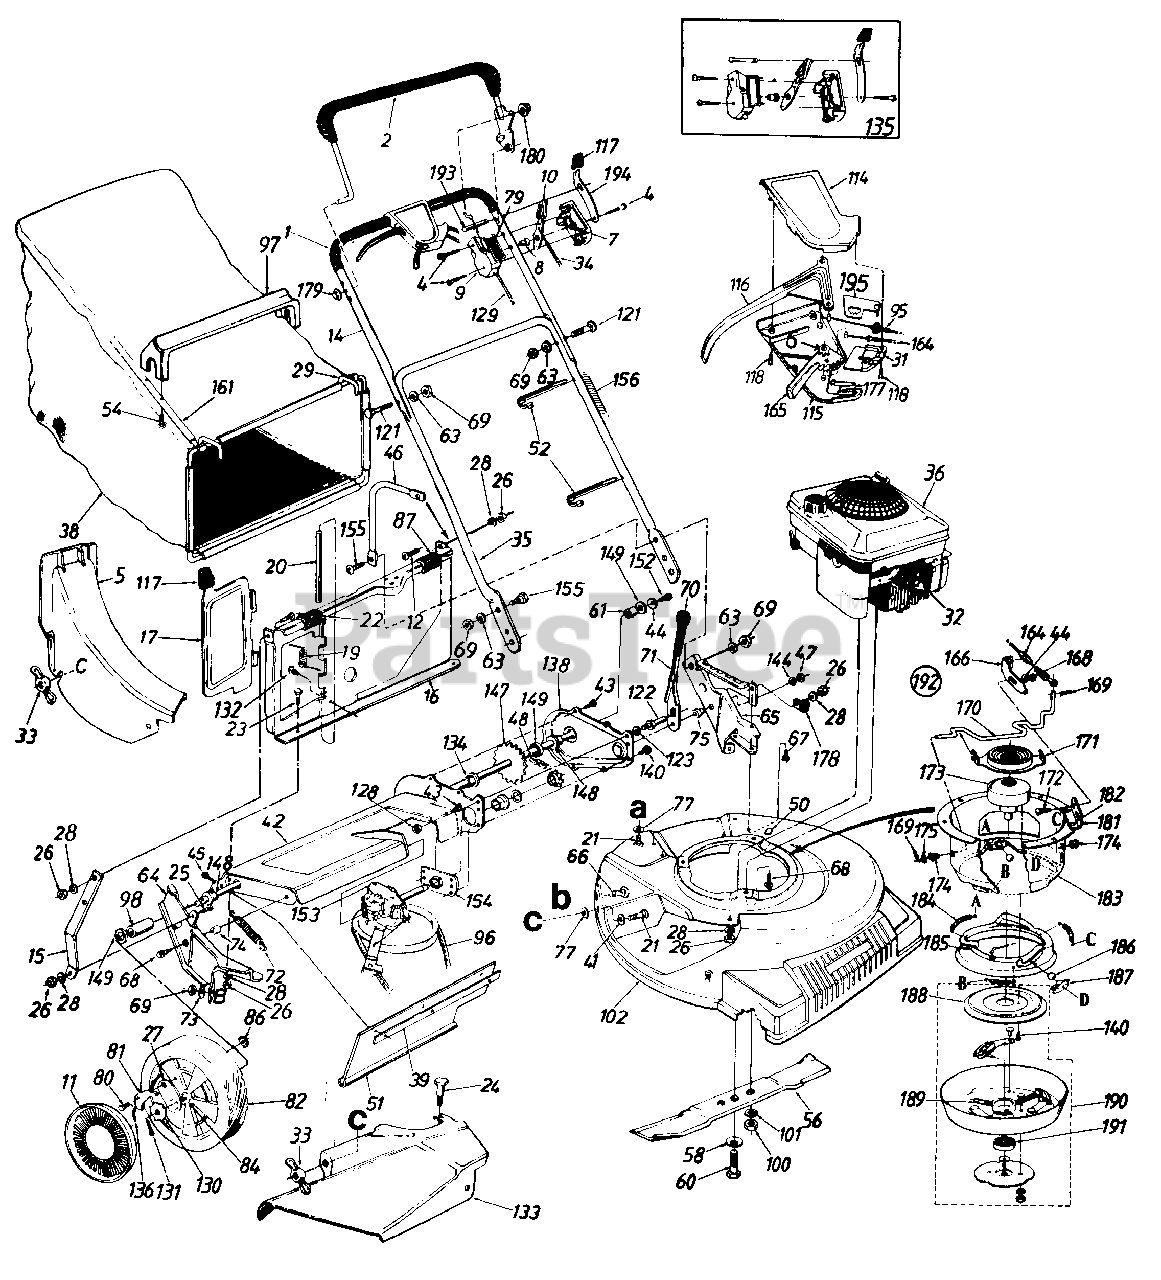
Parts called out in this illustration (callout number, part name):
1	Grip
2	Control Handle Ass'y. L.H.
4	Truss Mach. Scr. #12 x 1.50" Lg.
5	Rear Discharge Chute Ass'y.
6	3 Tooth Rack Gear Insert
7	Control Panel Half
8	Control Disc Pin
9	Clutch Panel Half
10	Throttle Control Lever
11	Hub Cap
12	Truss Mach. Scr. 1/4-20 x .62" Lg.
14	Upper Handle
19	Torsion Spring
20	Pivot Pin
21	Carriage Bolt 1/4-20 x .62"
22	Truss Mach. Scr. 1/4-20 x .75" Lg.
23	Hex Bolt 1/4-20 x .5" Lg.
24	Shoulder Bolt Special
25	Hex Bolt 1/4-20 x .62" Lg.
26	Hex Nut 1/4-20 Thd.
27	Pawl Plate
28	L-Wash. 1/4" I.D.
31	S.P. Control Cover
32	Spark Plug Insulator
33	Wing Nut
34	Throttle Control Wire 61"
35	Lower Handle
36	Engine
38	Grass Bag
39	Retaining Strip
41	Fl-Wash. .344" I.D. x .62".
44	Bell-Wash. 1/4" I.D.
45	Hex AB-Tap Scr. 1/4 X .62"
46	Catcher Panel Support Brkt.
47	Hex Patch L-Nut 3/8-24 Thd.
48	#48 Chain .500" Pitch x 30 Links
51	Rear Flap 3.75" x 17.30" Lg.
52	Cable Tie
54	Hex AB-Tap Scr. #12 x 1.25" Lg.
56	21" Blade
58	Bell-Wash..46" I.D.
60	Hex Bolt 7/16-20 x 2.0"
61	Spacer.513" I.D.
63	L-Wash. 5/16" I.D.
64	R.H. Handle Wheel Brkt. Ass'y.
65	L.H. Handle Wheel Brkt. Ass'y.
66	Carriage Bolt 5/16-18 x .62"
67	Hex B-Tap Scr. 5/16-18
68	Hex TT-Tap Scr. 3/8-16
69	Hex Nut 5/16-18 Thd.
71	Height Adj. Lever
72	Extension Spring 3.80" Lg.
73	Bell-Wash. 5/16" I.D.
74	Spacer.383" I.D.
75	Shld. Spacer .5" Dia.
77	Bolt Retainer 1/4 X .50" O.D.
79	Control Label
80	Shld. Scr. .342" Dia. x .268
81	Pawl
82	Wheel Ass'y. Comp. Rear
84	Sleeve Bearing 1/2" I.D.
86	Flat Nut 1/4-20 Thd.
87	Panel Clip
95	S.P. Cable 50" Lg.
96	"V"-Belt
97	Bag Handle
98	Sleeve.526" I.D.
100	Hex Nut 3/8-24 Thd. (Gr. 8)
101	L-Wash. 3/8" I.D.
115	Self-Propelled Control Cover
116	Control Lever
117	Door Grip
118	Fl-"C"-Sunk Hd. Tap Scr. #10 x .75' Lg.
121	Curved Carr. Bolt 5/16-18 x 1.38" Lg.
122	Shld. Pin 1.43" Lg.
123	L-Wash. 3/8" I.D.
128	Hex Jam Nut 3/8-24 Thd.
129	Control Cable 49"
130	Ratchet Wheel 1.62" O.D.
131	Cotter Pin 1/8" Dia. x 1 "
132	Hex B-Tap Scr. #10 x .38" Lg.
133	Side Chute Deflector Ass'y.
134	Hex Flange Bearing
135	Kit Control Housing Comp.
136	Spring Nylon
144	Fl-Wash. .385" I.D. x .87"
147	Rear Shaft Ass'y. 21.94" Lg.
148	Hex Flange Brg. .506" I.D.
149	Fl-Wash. .531" I.D. x .930"
152	Hex Bolt 1/4-20 x .62" Lg. (Grade 5)
153	Transmission Comp.
155	Truss Mach. Scr. 5/16-18 x .75" Lg.
156	Plastic Tubing
164	Spd. Control Cable 50" Lg.
165	6-Spd. Shift Lever
169	Cot-Pin 3/32" Dia. x .75" Lg.
170	Shift Rod
171	Movable Pulley Half Ass'y.
172	Carr. Bolt 1/4-20 x .5" Lg.
173	Fixed Pulley Adapter
174	Flanged Bushing
175	Fl-Wash. .328" I.D. x .68" O.D.
177	Shift Lever Spring
178	Clamp
179	Push Cap
180	Push Cap
181	6-Speed Cable Mtg. Brkt.
182	Rivet.252" Dia. x .31"
183	Clutch Housing
184	Ext. Spring 1.75" Lg.
185	Brake Cup Cone
186	Steel Ball .5" Dia.
187	Ball Block
188	Clutch Cone
189	Comp. Spring 2.0" Lg.
190	Clutch Blade Housing
191	Ball Brg. .669" I.D. x 1.574"
192	Blade Brake Clutch Ass'y. Comp.
193	Lock Pin
194	Lockout Spring
195	6-Speed Cable Rrliit.
